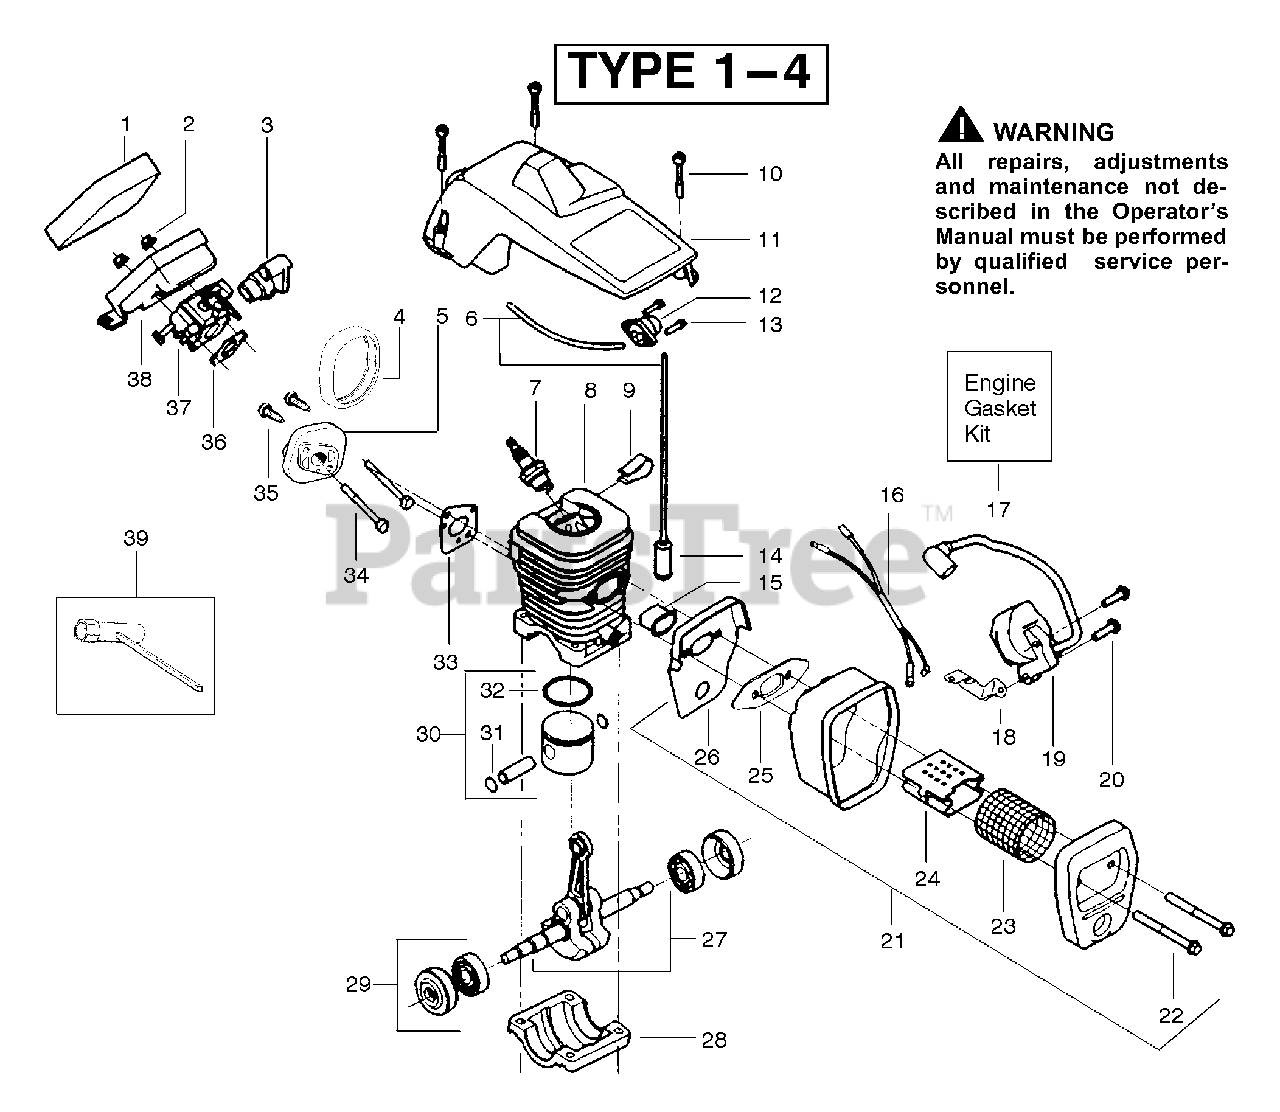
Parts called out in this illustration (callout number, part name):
1	Foam Air Filter
3	Grommet Carb Adjust
4	Seal Carb Adapter
5	Adapter Carb.
6	Kit Fuel Line (Small)
7	Spark Plug (RCJ7Y)
8	Kit Cylinder
9	Clip High Tension Lead
11	Shield Cylinder
12	Assy Air Purge
14	Assy Fuel Pickup
15	Insulator Heat
16	Assy.Wire Harness
17	Kit Engine Gasket
18	Strap Ground
19	Module Ignition
21	Assy Muffler
23	Screen Spark
24	Diffuser Muffler
25	Gasket Muffler (kit)
26	Backplate Muffler
27	Assy. Crankshaft
28	Cap Crankcase
29	Assy. Seal & Bearing
30	Kit Piston
31	Retainer Piston Pin
32	Ring Piston
33	Gasket Adapter (kit)
36	Gasket Carb. (kit)
37	Kit Carburetor-(WT 324)
38	Housing Air Filter
39	Wrench Bar
